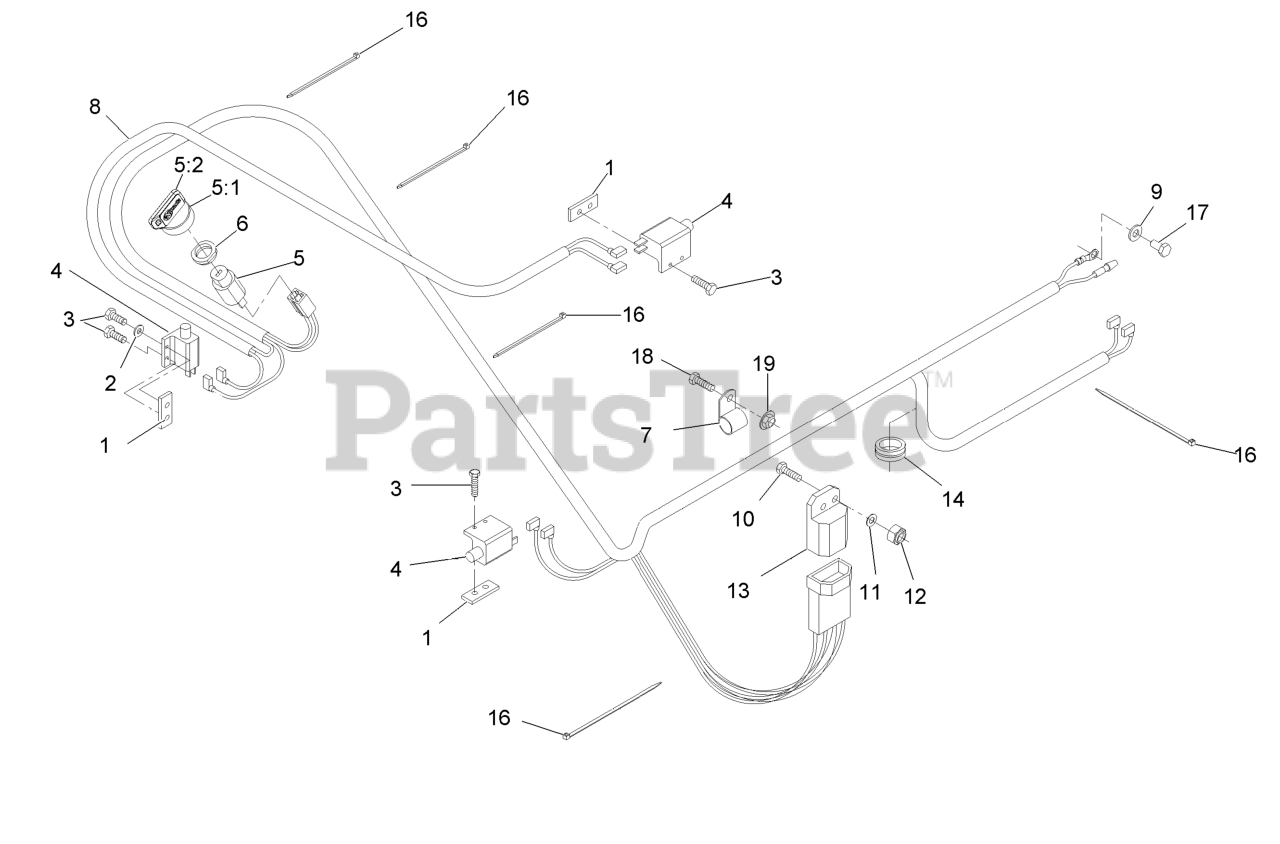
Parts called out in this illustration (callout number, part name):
1	PLATE-TAPPED
2	WASHER-FLAT
3	SCREW-PPH
4	SWITCH-OPEN, NORMALLY
5	SWITCH & KEY (INCLUDES NU
5:1	KEYS-IGNITION (SPARE PAIR
5:2	KEY-IGNITION
6	NUT-SWITCH, IGNITION
7	CLIP-LOOM
8	HARNESS-WIRING
9	WASHER-PLAIN
10	SCREW-HH
11	WASHER-FLAT
12	NUT-LOCK, NI
13	MODULE-INTERLOCK
14	GROMMET
16	TIE-CABLE
17	SCREW-HH
18	SCREW-HH
